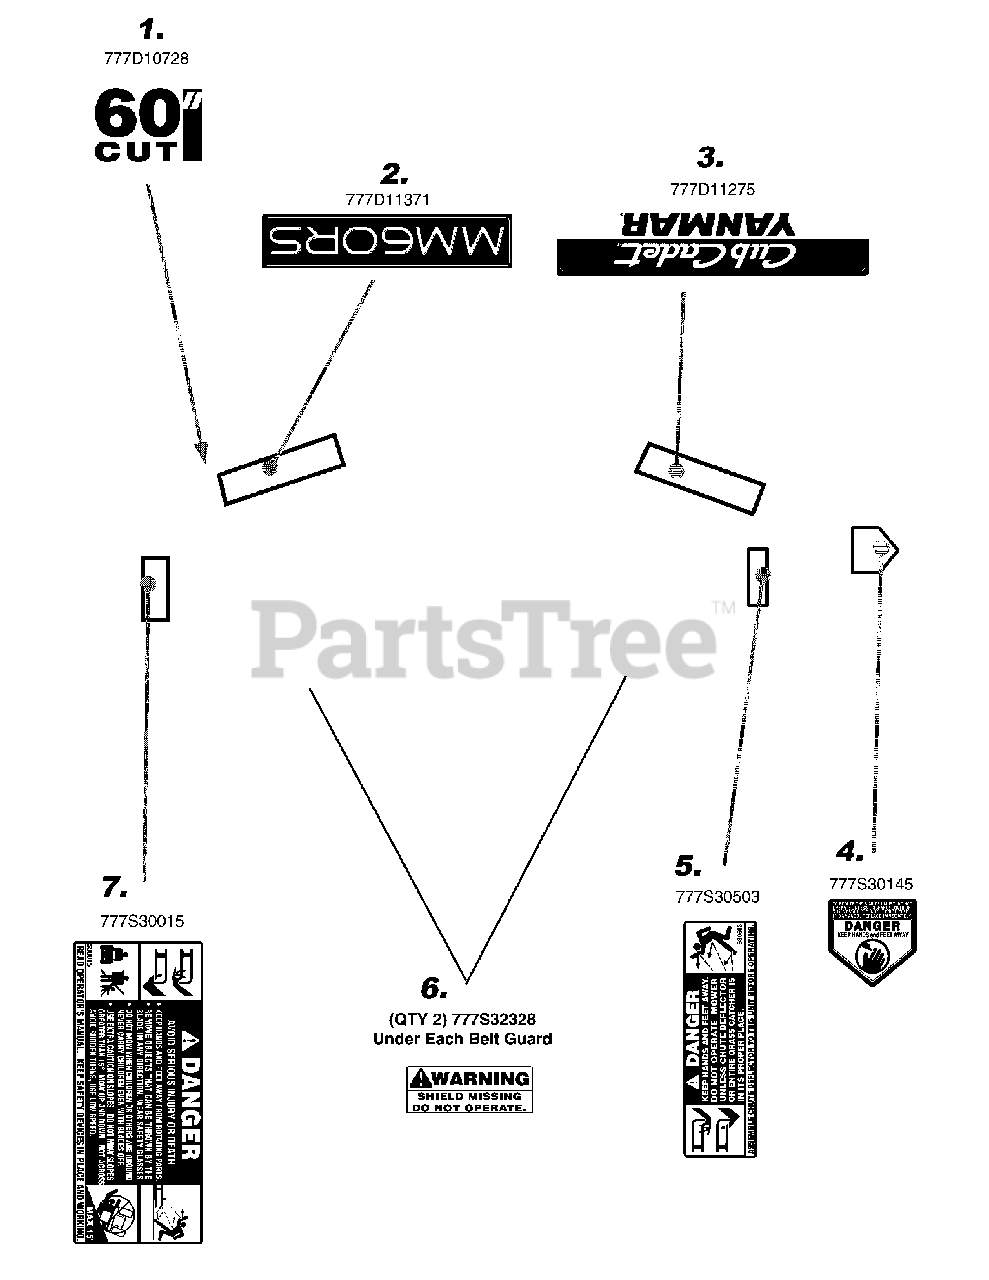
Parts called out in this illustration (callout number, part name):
1	LABEL-60" CUT
2	LABEL-MM60RS DECK
3	LABEL-CUB YANMAR
4	LABEL
5	LABEL-DANGER CHUTE
6	DECAL-WARNING
7	LBL.RIDER DNGR.STRAIGT
